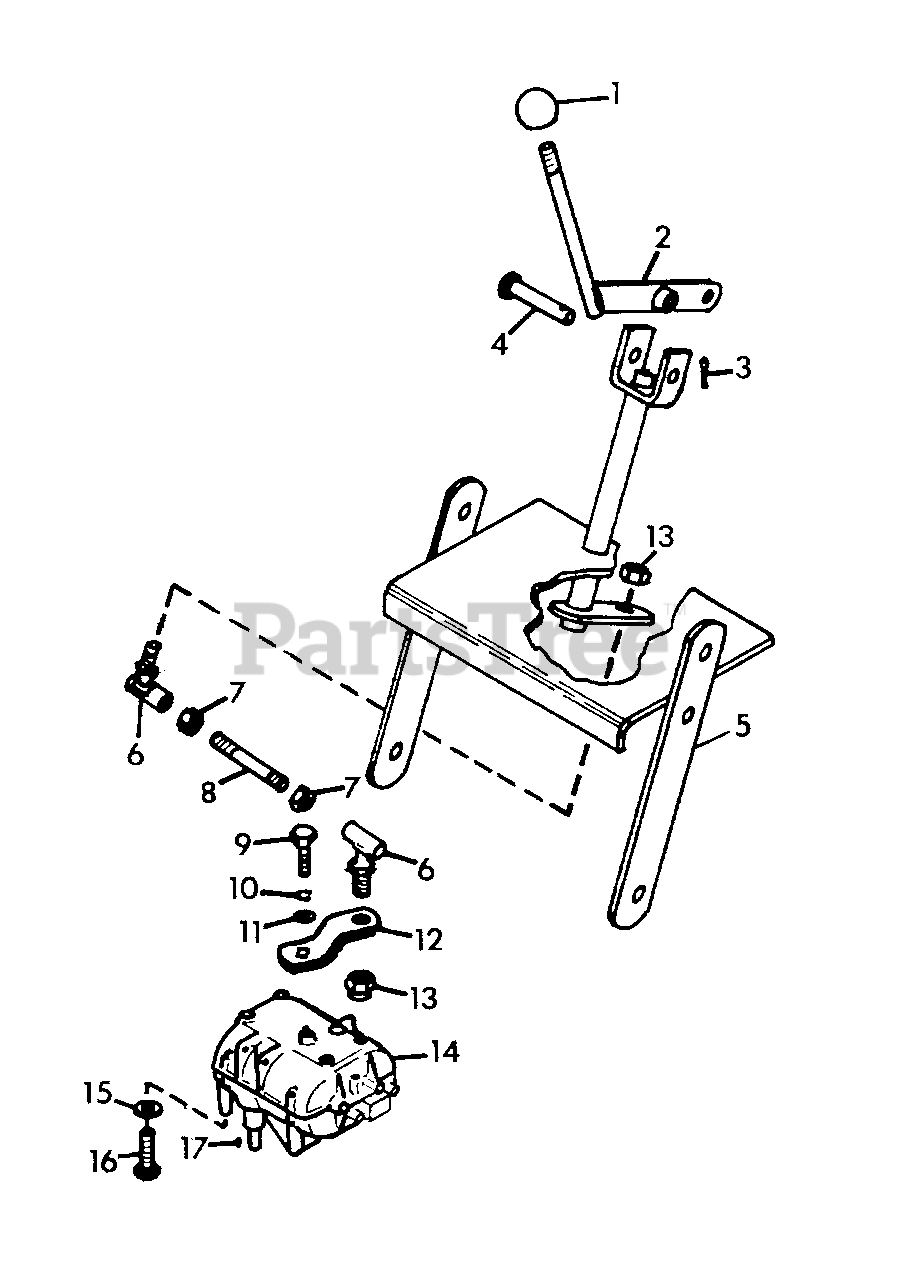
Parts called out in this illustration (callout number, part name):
1	KNOB, CONTROL
2	WELDMENT, SHIFT LEVER
3	PIN, COTTER .09X.625
4	PIN, CLEVIS
5	WELDMENT, SHIFTER
6	BALL JOINT, DISCONNECTING
7	NUT, HEX 1/4-28
8	ROD, TRANS. SHIFTER
9	BOLT, HEX 1/4-28X.50
10	WASHER, LOCK 1/4
11	WASHER, FLAT .281X.625X.065
12	ARM, TRANS. SHIFT
13	NUT, LOCK 1/4-28
14	TRANSMISSION, 5-SPEED
15	WASHER, FLAT .344X.688X.065
16	BOLT, HEX 5/16-18X.75
17	KEY, WOODRUFF .187X.750 HARD
